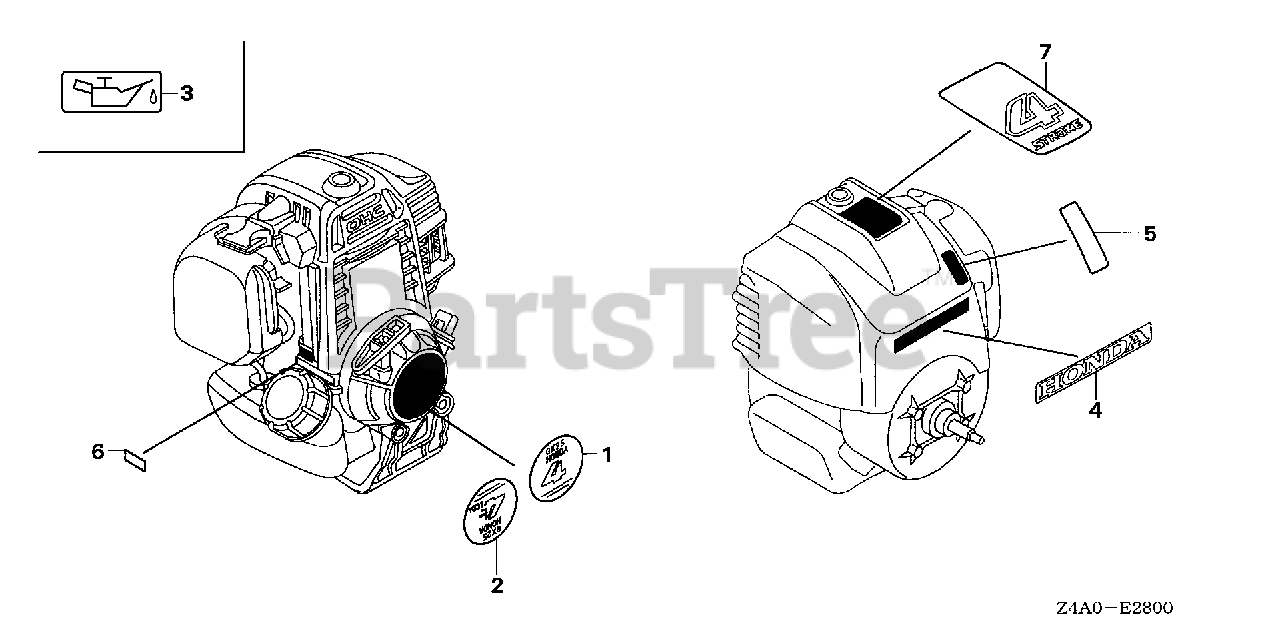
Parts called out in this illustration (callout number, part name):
1	MARK, EMBLEM
4	MARK, HONDA
6	MARK, TYPE (ST3)
7	MARK (4-STROKE)
